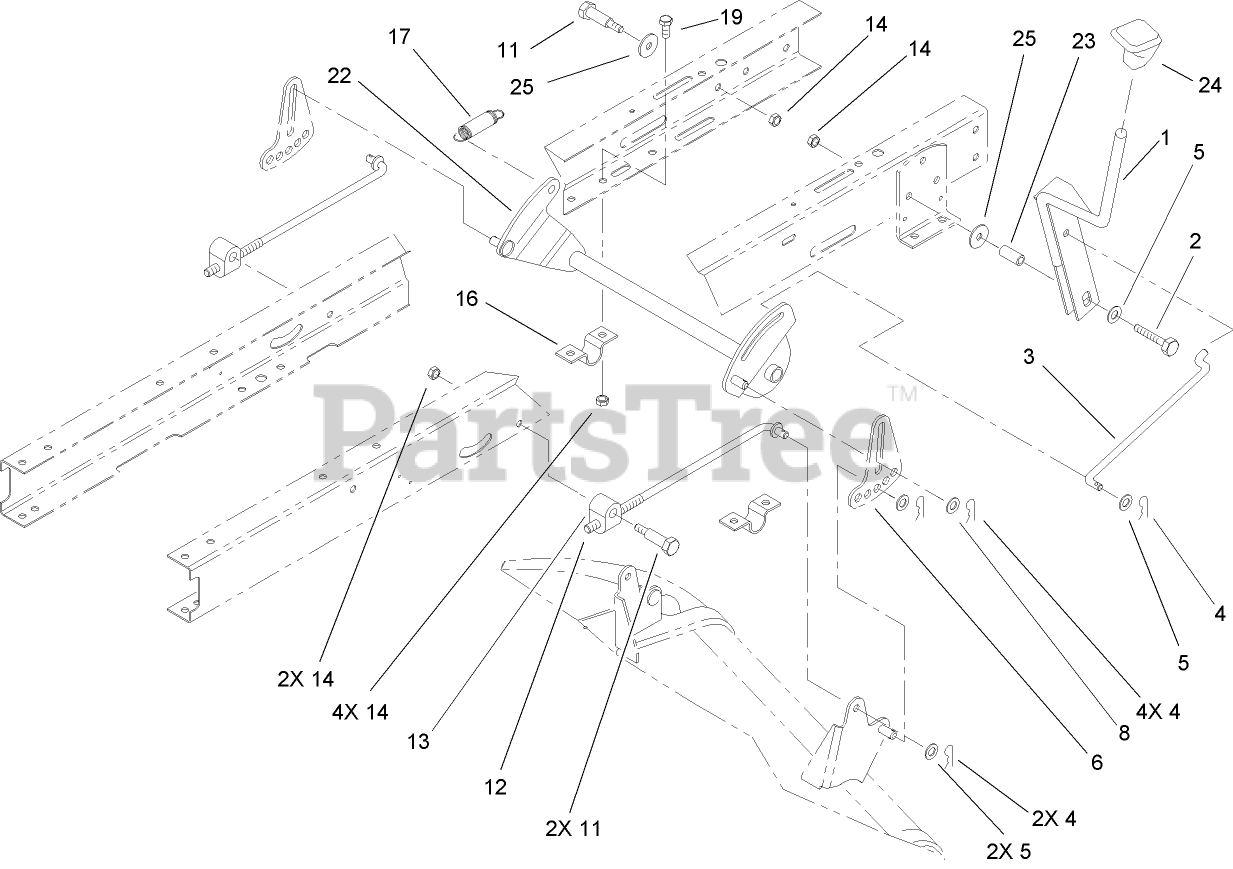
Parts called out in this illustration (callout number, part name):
2	SCREW-HH
3	LINK-HOC
5	WASHER-FLAT
6	LINK-ADJUSTING, HOC
8	WASHER-HARDENED
11	SCREW-SHOULDER, HH
12	ROD-HANGER, REAR
13	TRUNNION-HOC
14	NUT-LOCK, NI
16	CLAMP-PIVOT, HOC
17	SPRING-EXTENSION
19	SCREW-HH
22	PIVOT ASM
23	SPACER
24	KNOB-SHIFT
25	WASHER-PIVOT
